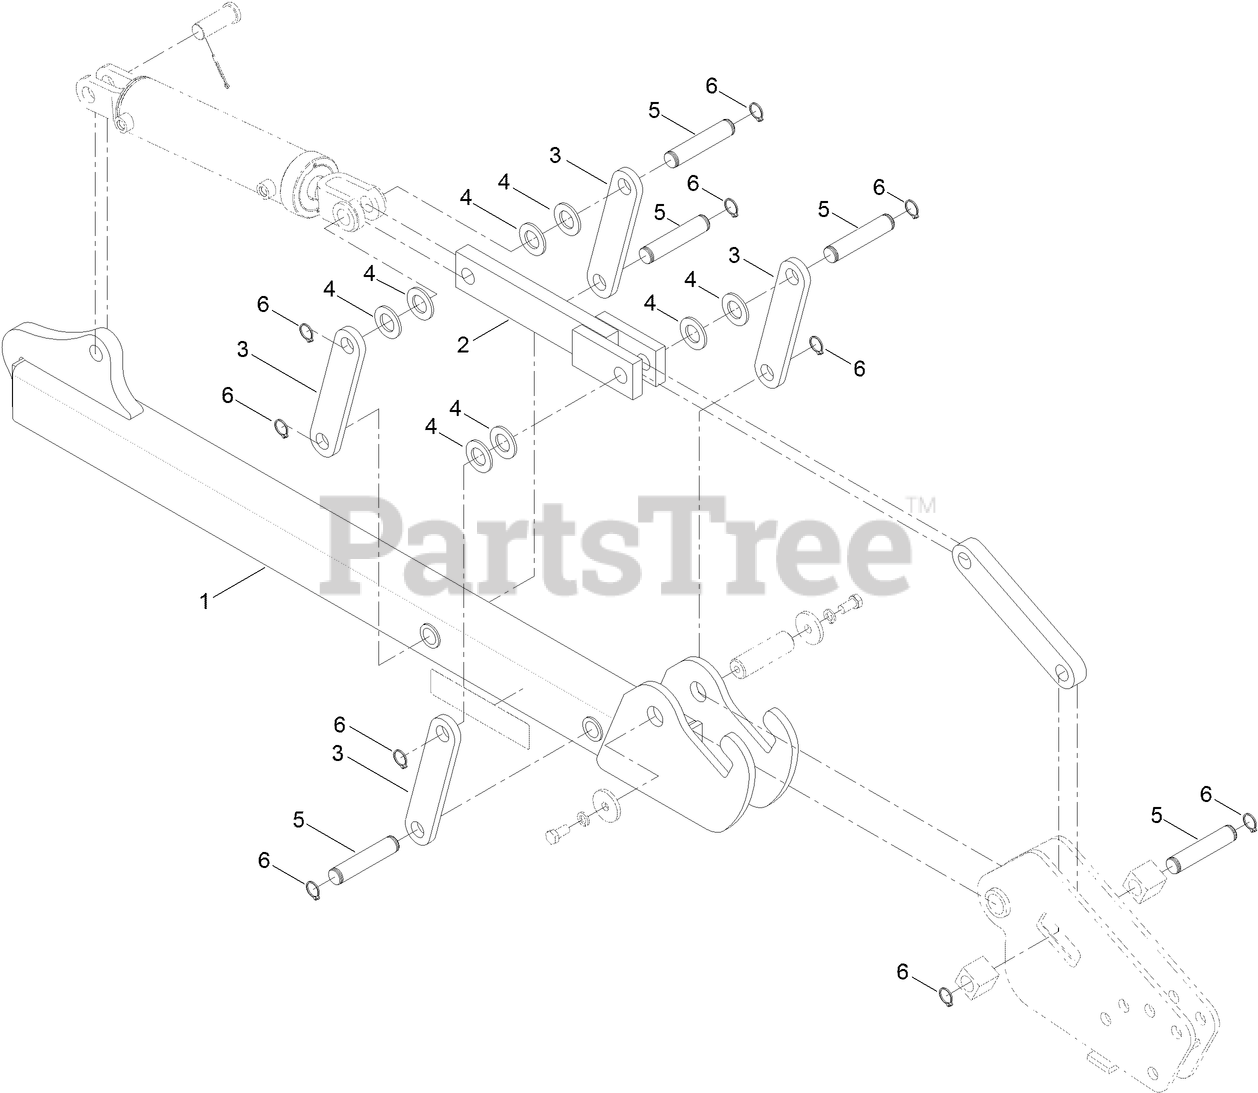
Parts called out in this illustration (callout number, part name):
1	TUBE-CRUMBER, 5 FT
2	BAR-EXTENSION, 5 FT
3	LINK-CRUMBER, STRAIGHT
5	PIN-CYLINDER, ROD
6	RING-RETAINING
